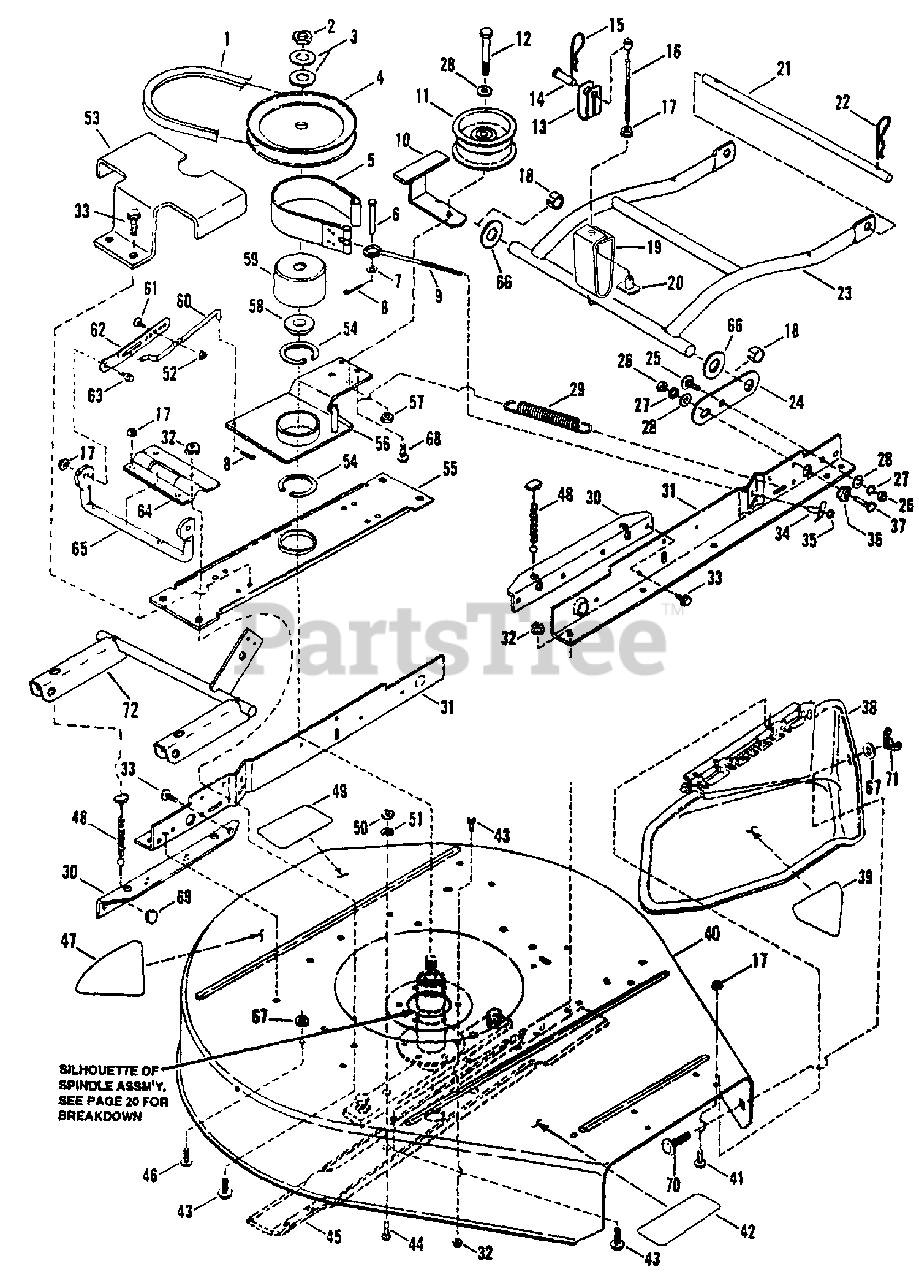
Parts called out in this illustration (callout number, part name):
1	BELT, 30" Drive, 55.25" EL
2	NUT, 3/4-16 Hex Jam
3	WASHER, Flat
4	PULLEY, Spindle, 6 1/2" O.D.
5	BAND, Brake Assembly
6	PIN, 1/4 x 1 1/4" Clevis
7	WASHER, Flat
8	COTTER-PIN, 3/32 x 3/4"
9	BOLT, 1/4-20 Eye
10	GUIDE, Belt
11	PULLEY, Idler, 4" O.D.
12	BOLT, 3/8-16 x 1 3/4" Hex Head
13	BRACKET, Front Lift Cable
14	PIN, 3/8 x 1 1/16" Clevis
15	PIN, 3/32 x 1 19/32" Hair
16	CABLE, Deck lift, Front
17	NUT, 5/16-18 Hex Flange Lock
18	RING, Red
19	BRACKET, Front Lift Hanger
20	T-NUT, 5/16-18 Thread
21	PIN, Front Deck Hanger
22	PIN, .148 x 2.62" Hair
23	LIFT, Front Arm
24	LINK, Adjustment
25	BOLT, 3/8-16 x 3/4" Carriage
26	NUT, 3/8-16 Hex
27	WASHER, 3/8 Split Lock
28	WASHER, 3/8 SAE
29	SPRING, Clutch & Brake
30	BRACKET, Deck Hanger
31	RAIL, 30" Deck
32	NUT, 3/8-16 Hex Flange Lock
33	SCREW, 5/16-18 x 5/8" Self-Tapping
34	T-NUT, 1/4-20 Thread
35	NUT, 1/4-20 Hex
36	ECCENTRIC, Leveling
37	SCREW, 3/8-16 x 1" Hex Head Cap
38	ASSEMBLY, Deflector
39	DECAL, DANGER (Cut Finger)
40	DECK, 30" Cutting
41	BOLT, 5/16-18 x 1/2" Hex Flange Lock
42	DECAL, CAUTION
43	BOLT, 3/8-18 x 3/4" Hex Flange Lock
44	SCREW, 1/2-20 x 1" Hex Head Cap
45	BLADE, 30" Mower Deck
46	BOLT, 5/16-18 x 3/4" Hex Flange Lock
47	DECAL, 30 Inch
48	CABLE, Deck Lift, Rear
49	DECAL, CAUTION (Rotating Blades)
50	NUT, 1/2-20 Hex Jam
51	WASHER, 1/2 Internal Tooth Lock
52	NUT, 1/4-20 Hex Flange Lock
53	GUIDE, Belt
54	RING, 2" External Retaining
55	BRACE, Spindle
56	ARM, Idler
57	NUT, 3/8-16 Hex Center Lock
58	WASHER, Spindle
59	DRUM, Brake
60	ROD, Link, Clutch/Brake
61	BOLT, 1/4-20 x 1/2" Hex Flange Lock
62	BRACKET, Link, Clutch/Brake
63	SCREW, 5/16-18 x 3/4" Shoulder
64	BRACKET, Pivot Arm
65	ARM, Pivot
66	WASHER, Flat
67	WASHER, 5/16 Flat
68	SCREW, 5/16-18 x 3/4" Self-Tapping
69	PLUG
70	BOLT, 5/16-18 x 3/4" Short Neck Carriage
71	WING-NUT, 5/16-18
72	LIFT, Rear Arm
